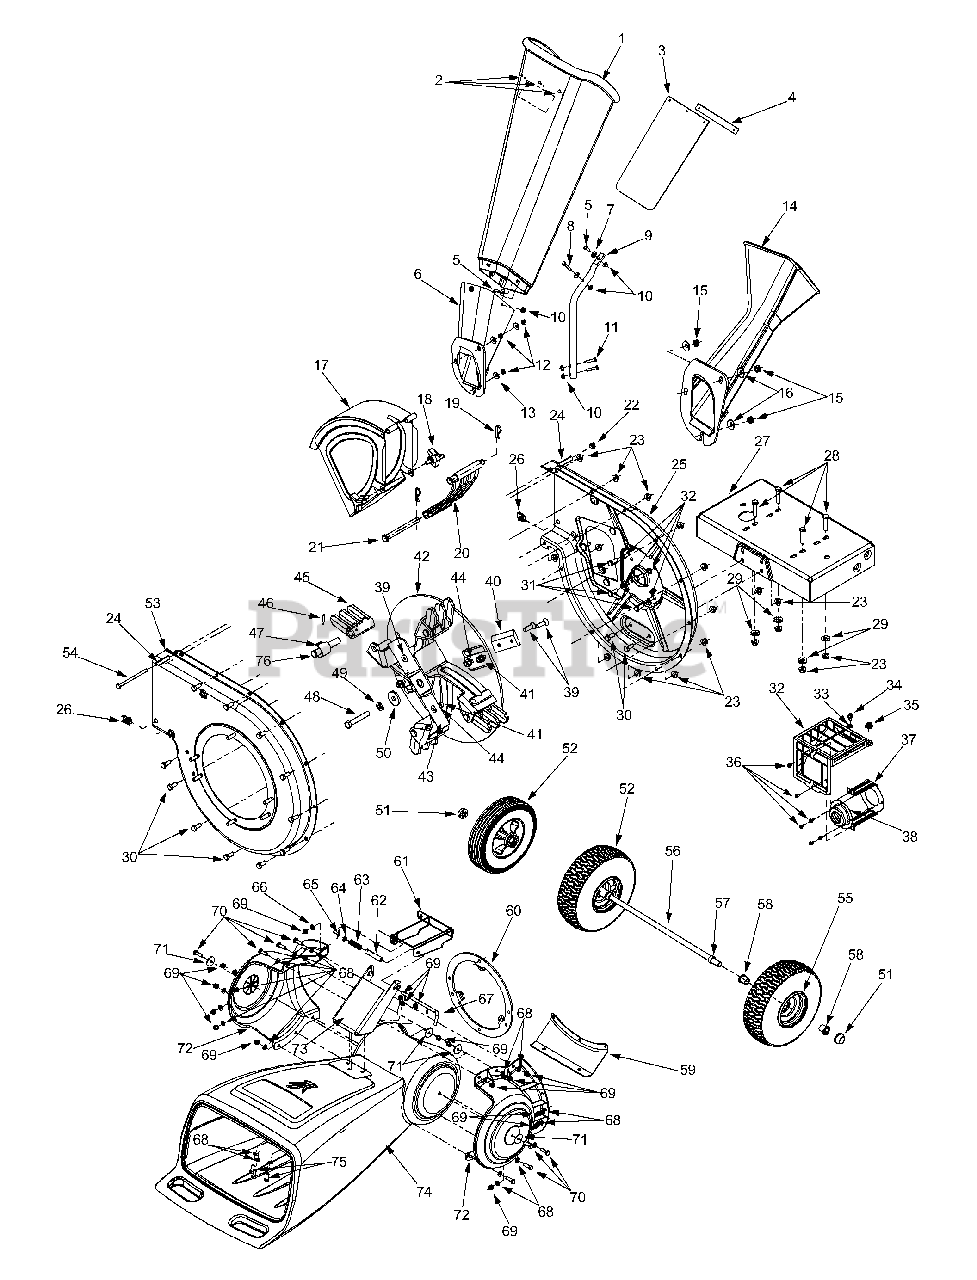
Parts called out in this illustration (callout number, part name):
1	Chipper Chute
2	Pop Rivet
3	Chute Flap
4	Flat Strip
5	Hex Cap Screw 1/4-20 x .620
8	Hex Cap Screw 1/4-20 x 1.25
10	Hex Flange Nut 1/4-20
11	Hex Cap Screw 1/4-20 x 1.25
12	Hex Nut 5/16-18
13	Bell Washer.340 ID x .872 OD
15	Hex Nut 5/16-18
16	Bell Washer .340 ID x .872 OD
18	Knob 5/16-18
19	Cotter Pin
21	Clevis Pin
22	Hex Lock Nut 1/4-20
23	Flange Hex Lock Nut 5/16-18
24	Spacer
26	U Nut 5/16-18
28	Hex Cap Screw 5/16-18 x 1.5
29	Bell Washer 5/16 x 1.0
30	Hex Cap Screw 5/16-18 x .75
31	Hex Cap Screw 5/16-24 x .75
32	Lock Washer 5/16
33	Lock Washer 1/4
34	Hex Washer Screw 1/4-20 x .5
35	Hex Lock Nut 5/16-18
36	Hex Washer Screw
37	Muffler Bracket Guard
38	Deflector
39	Flat Screw 5/16-24 x 1.0
40	Chipper Blade
41	Hex Lock Nut 5/16-24
42	Impeller Asm
43	Shredder Blade
44	Lock Washer 5/16
45	Flail Blade
46	Spiral Pin
47	Spring Pin
48	Hex Cap Screw 3/8-24 x 2.25
49	Lock Washer 3/8
50	Flat Washer 3/8 x 1.25
51	Push Cap
52	Wheel Assy Comp 10.0 x 2.5
54	Hex Cap Screw 1/4-20 x 3.75
57	Spacer
58	Flange Bearing
62	Spacer
63	Compression Spring
64	Flat Washer 3/8 x .620 x .033
65	Cotter Pin
66	Flat Washer
67	Release Rod
68	Flat Washer .330 ID x .630 OD
69	Hex Lock Nut 5/16-18
70	Hex Cap Screw 5/16-18 x 1.0
71	Flat Washer .320 ID x 1.25 OD
72	Collar-Hopper
74	Hopper
75	Hex Cap Screw 5/16-18 x .75
76	Clevis Pin
